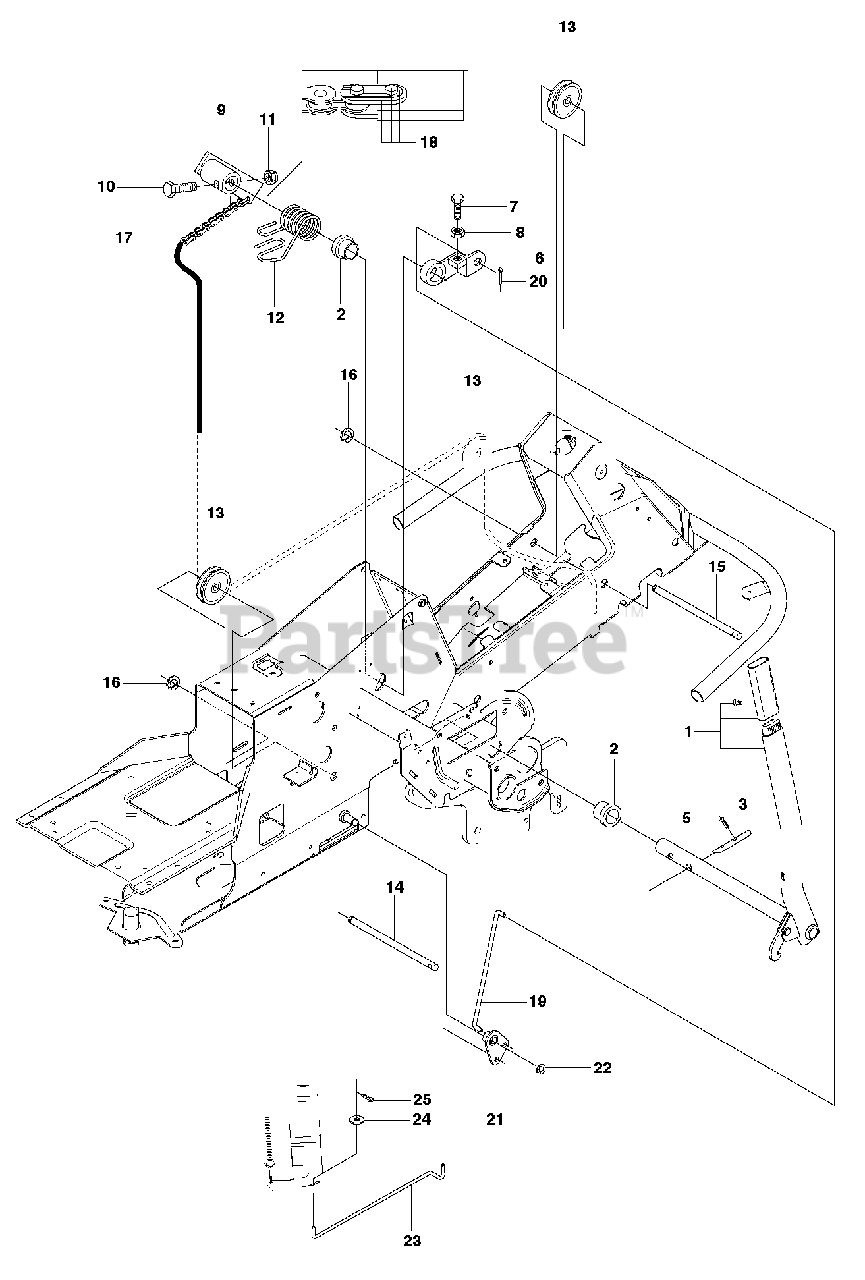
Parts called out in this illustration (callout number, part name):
1	LIFTING LEVER ASSY
2	BUSH
5	SPLIT PIN
6	LEVER CLUTCH
9	LIFTING ARM
16	LOCK RING
19	CONNECTION ROD
20	SPLIT PIN
22	RETAINING RING
23	CONNECTION ROD
25	SPLIT PIN
